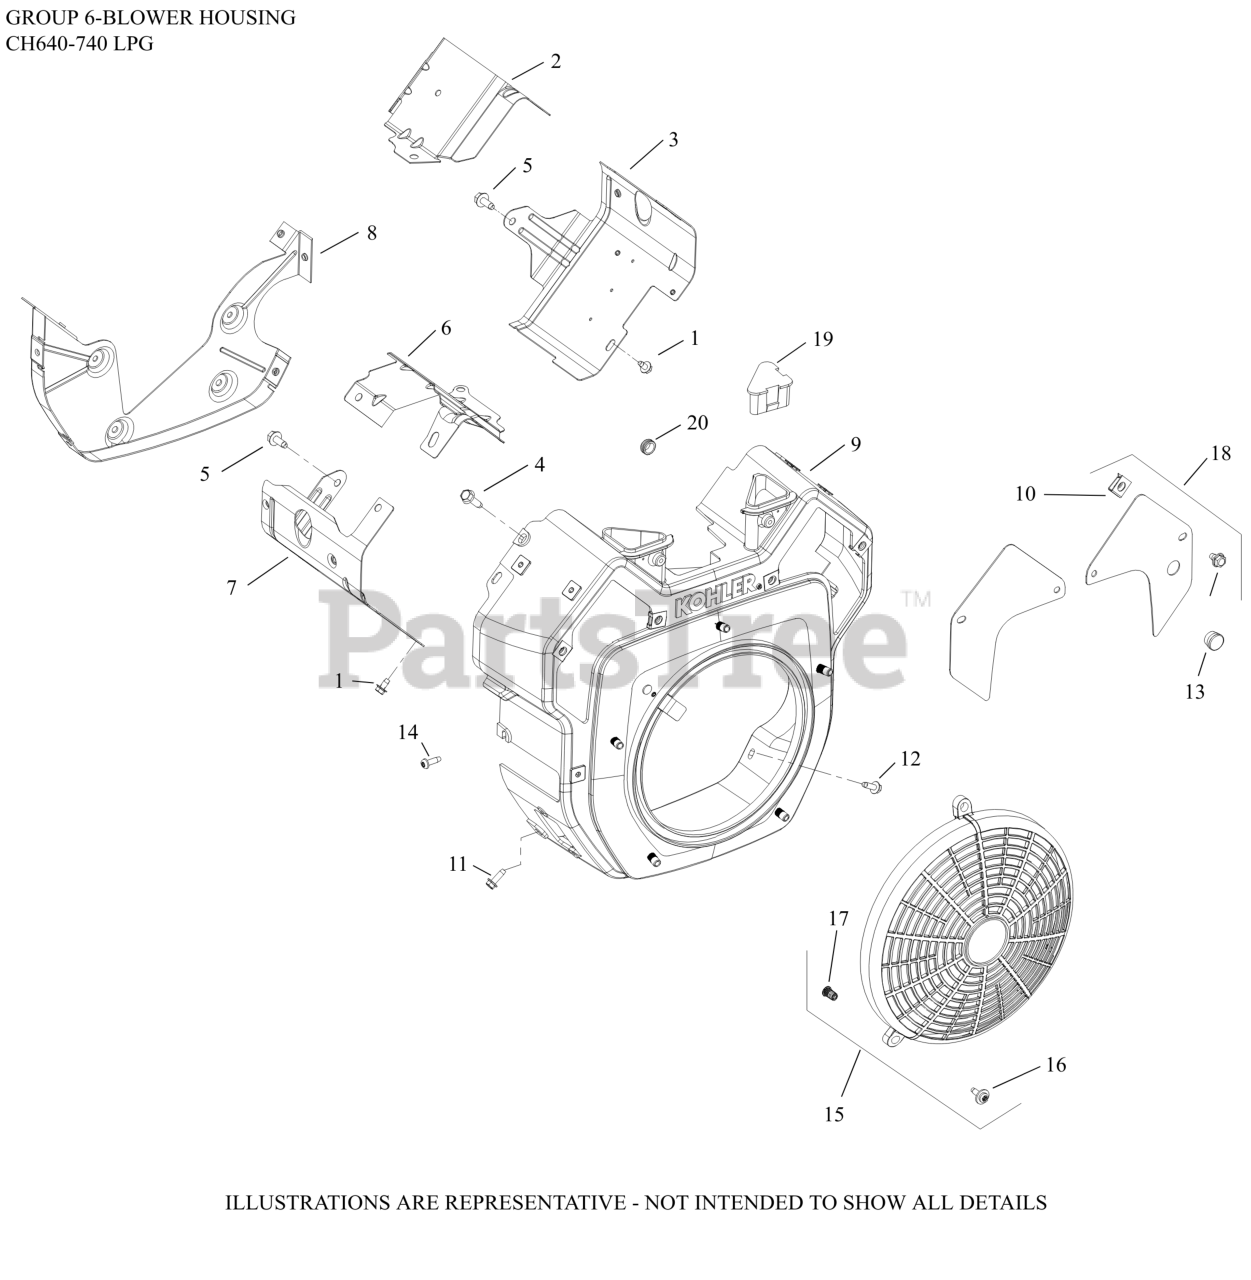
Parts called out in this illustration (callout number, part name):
1	SCREW, THREAD FORMING
2	BAFFLE, VALLEY #1 CYLINDER
3	KIT, CYL BAFFEL #1 SIDE
4	SCREW, THREAD FORMING
5	SCREW, THREAD FORMING
6	BAFFLE, VALLEY #2 CYLINDER
7	BAFFLE, LEFT BARREL
8	KIT, BACKING PLATE
9	KIT, BLOWER HOUSING
11	SCREW, THREAD FORMING
12	SCREW, THREAD FORMING
19	COVER, BLOWER HOUSING
